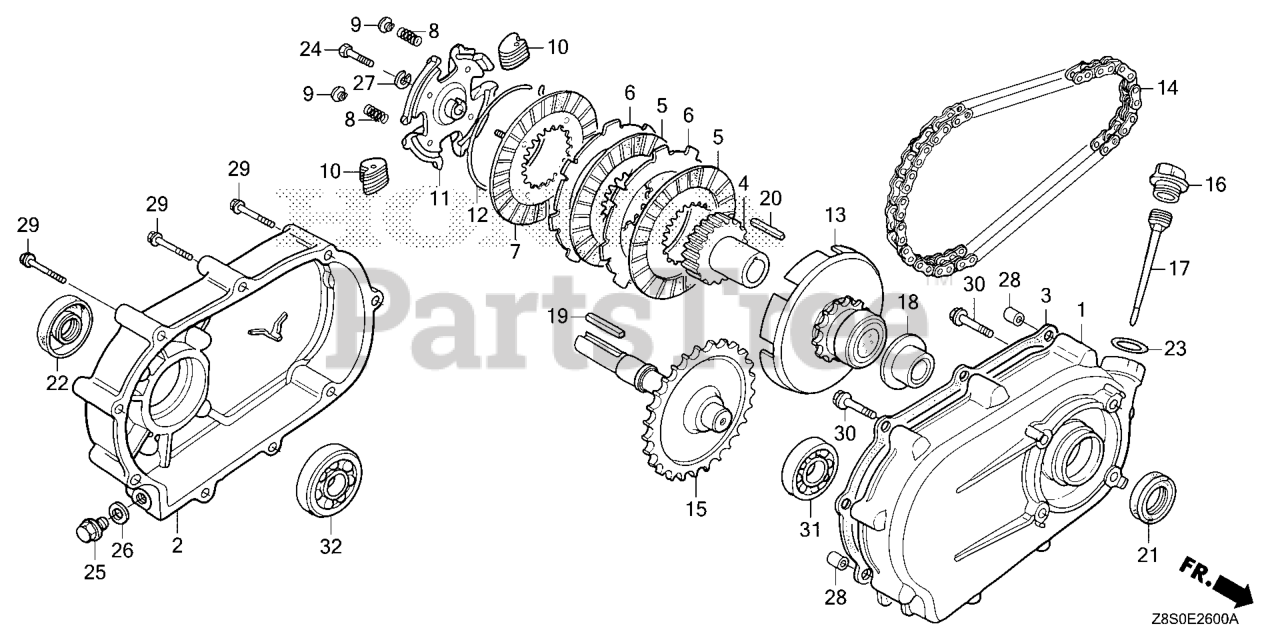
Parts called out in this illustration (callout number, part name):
1	CASE, REDUCTION
2	COVER, REDUCTION
3	GASKET, REDUCTION COVER (NINGBO SIL GASKET)
3	GASKET, REDUCTION COVER
4	CENTER, CLUTCH
5	DISK, CLUTCH FRICTION
6	PLATE, CLUTCH
7	PLATE, CLUTCH PRESSURE
8	SPRING, CLUTCH FREE
9	HOLDER, CLUTCH SPRING
10	WEIGHT, CLUTCH
11	HOLDER, CLUTCH WEIGHT
12	CENTER, CLUTCH WEIGHT
13	SPROCKET, DRIVE (14T)
14	CHAIN, DRIVE (RK428SH-36LE)
15	SHAFT, P.T.O. (28T)
16	CAP, REDUCTION OIL (GRAY)
17	DIPSTICK, OIL
18	WASHER, THRUST (25MM)
19	KEY (7X7X33)
20	KEY, CLUTCH CENTER
21	OIL SEAL (30X46X8)
22	OIL SEAL (30X50X7)
23	O-RING (26X2.7)
24	BOLT, HEX. (8X35)
25	BOLT, DRAIN PLUG (12MM)
26	WASHER, DRAIN PLUG (12MM)
27	WASHER, SPRING (8MM)
28	PIN A, DOWEL (8X14)
29	BOLT, FLANGE (6X50)
30	BOLT, FLANGE (8X32)
31	BEARING, RADIAL BALL (6205)
32	BEARING, RADIAL BALL (6206)
